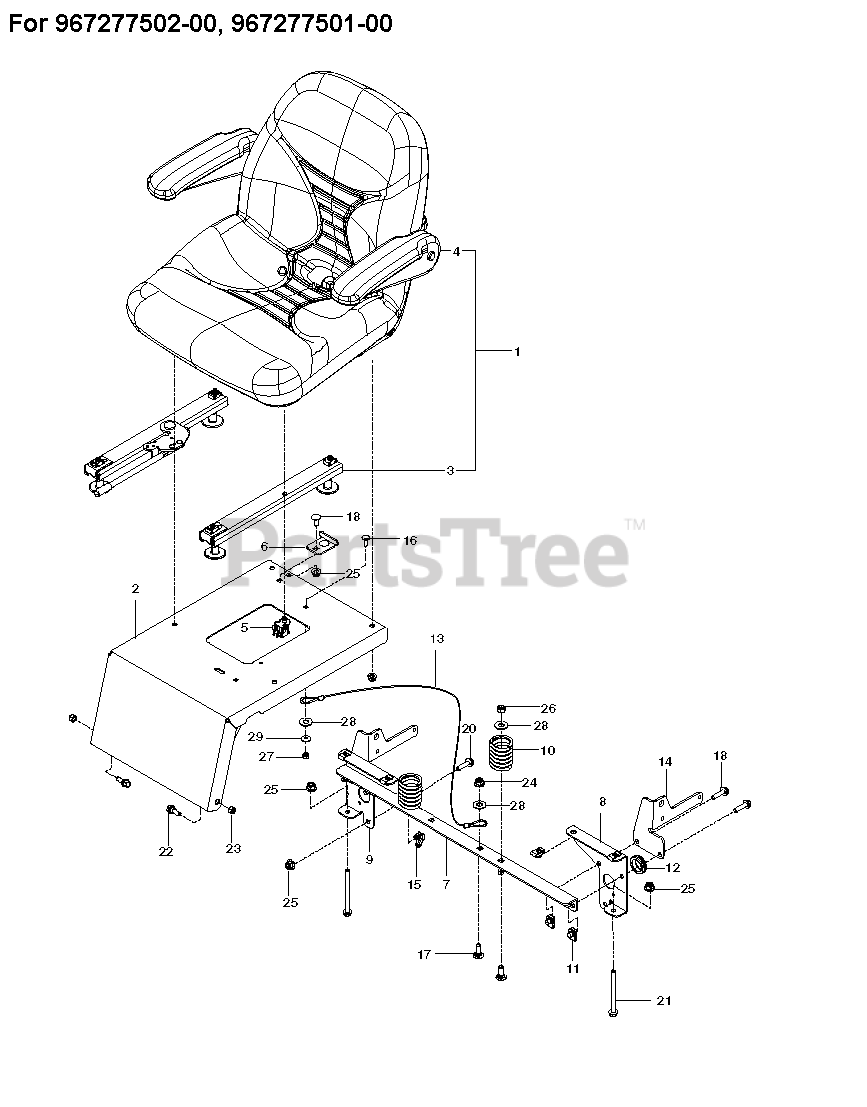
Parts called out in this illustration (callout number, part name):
1	SEAT
2	KIT.SEAT.MOUNT.W/DECAL
2	SUPPORT SEAT CONTROL ORANGE X6
3	TRACK ADJUSTMENT KIT
4	ARMREST KIT, LT SQUARE END
5	SWITCH.SNAPMOUNT.NC
6	STOP, SEAT - BLACK
7	SUPPORT, SEAT
8	SUPPORT, LT, BLK
9	SUPPORT, RT, BLK
10	SPRING, SEAT
11	U-CLIP 5/16-18 NUT RETAINER
12	RUBBER GROMMET
13	SEAT LANYARD
14	MOUNT, SEAT BELT, BLACK
15	TIE WRAP, 8-3/8", W/CLIP
16	RHSNB 1/4C X 3/4
17	RHSNB 3/8C X 1
18	RHSNB 5/16-18 X 3/4
20	HHFS 5/16-18 X 3/4
21	HHFS 5/16-18 X 3 3/4
22	SB 5/16-18 HEX HD GD5, BLK ZN
23	NUT 5/16 NYLOC
24	NUT 3/8-16 HEX FLG NYLOC ZD
25	5/16-18 NYLOC FLANGE NUT
26	NUT 3/8-16 NYLOC
27	NUT.1/4-20.HEX.NYLOC.ZD
28	WASHER 3/8 FLAT
29	WASHER 1/4 FLAT
